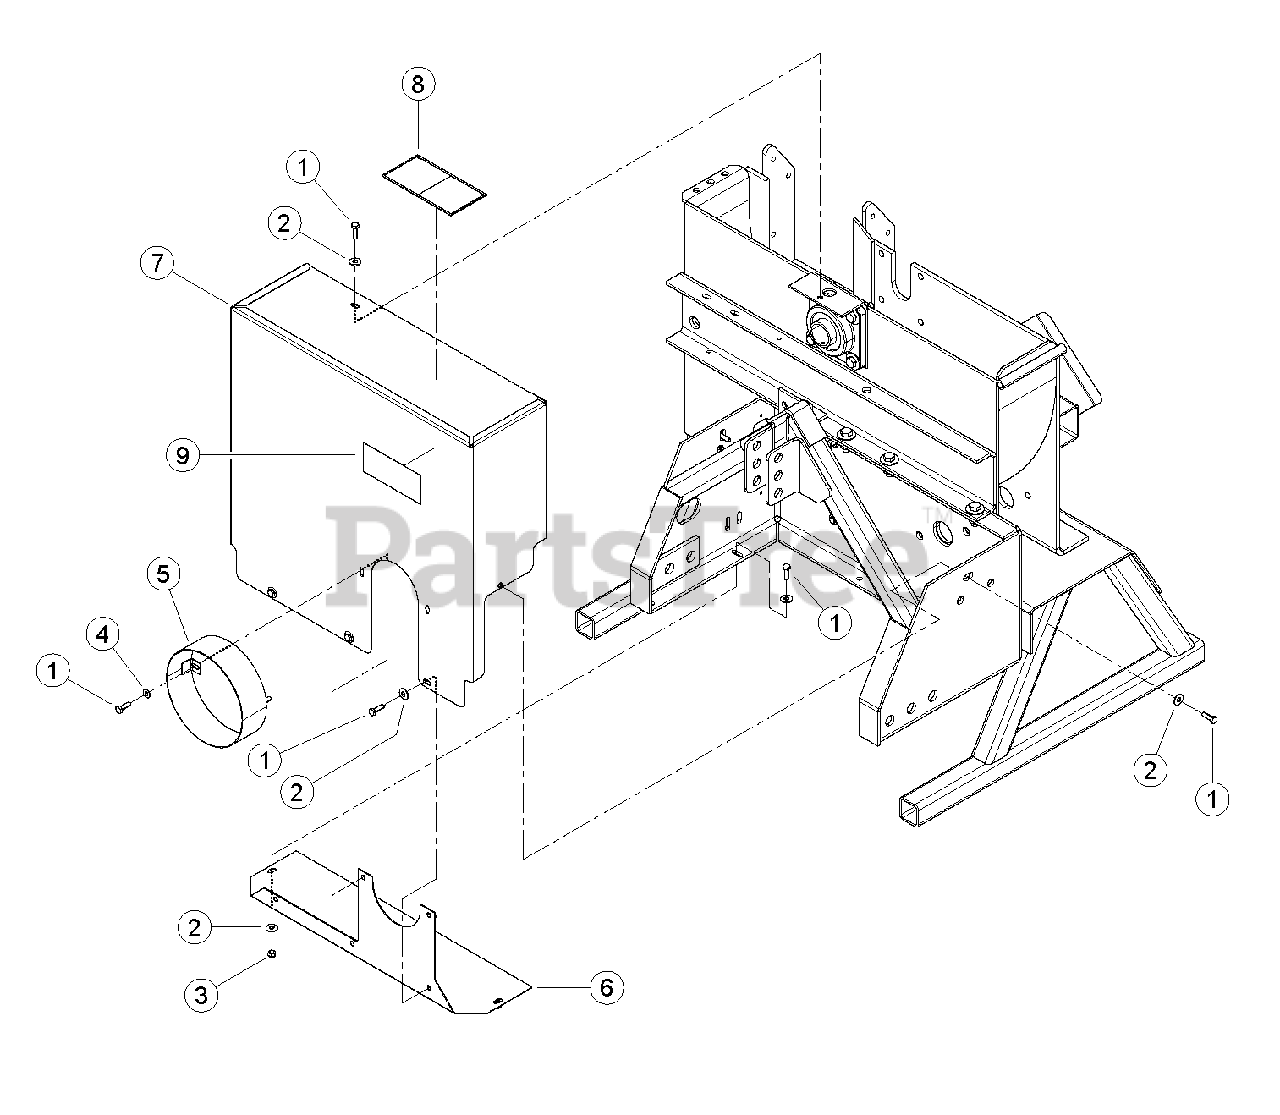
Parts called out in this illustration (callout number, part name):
1	BOLT, 5/16 X 1 GR5 HEX HD NC ZP
2	WASHER, 5/16 FLAT ZP
3	NUT, 5/16 NE NYLOCK ZP
4	WASHER, 5/16 SAE FLAT ZP
5	JOINT SHIELD WELDMENT
6	WELDMENT, LOWER BELT GUARD
7	ASSEMBLY, UPPER BELT GUARD SERVICE PART
8	DECAL, PTO DANGER ISO
9	DECAL, MUTILINGUAL MANUAL
